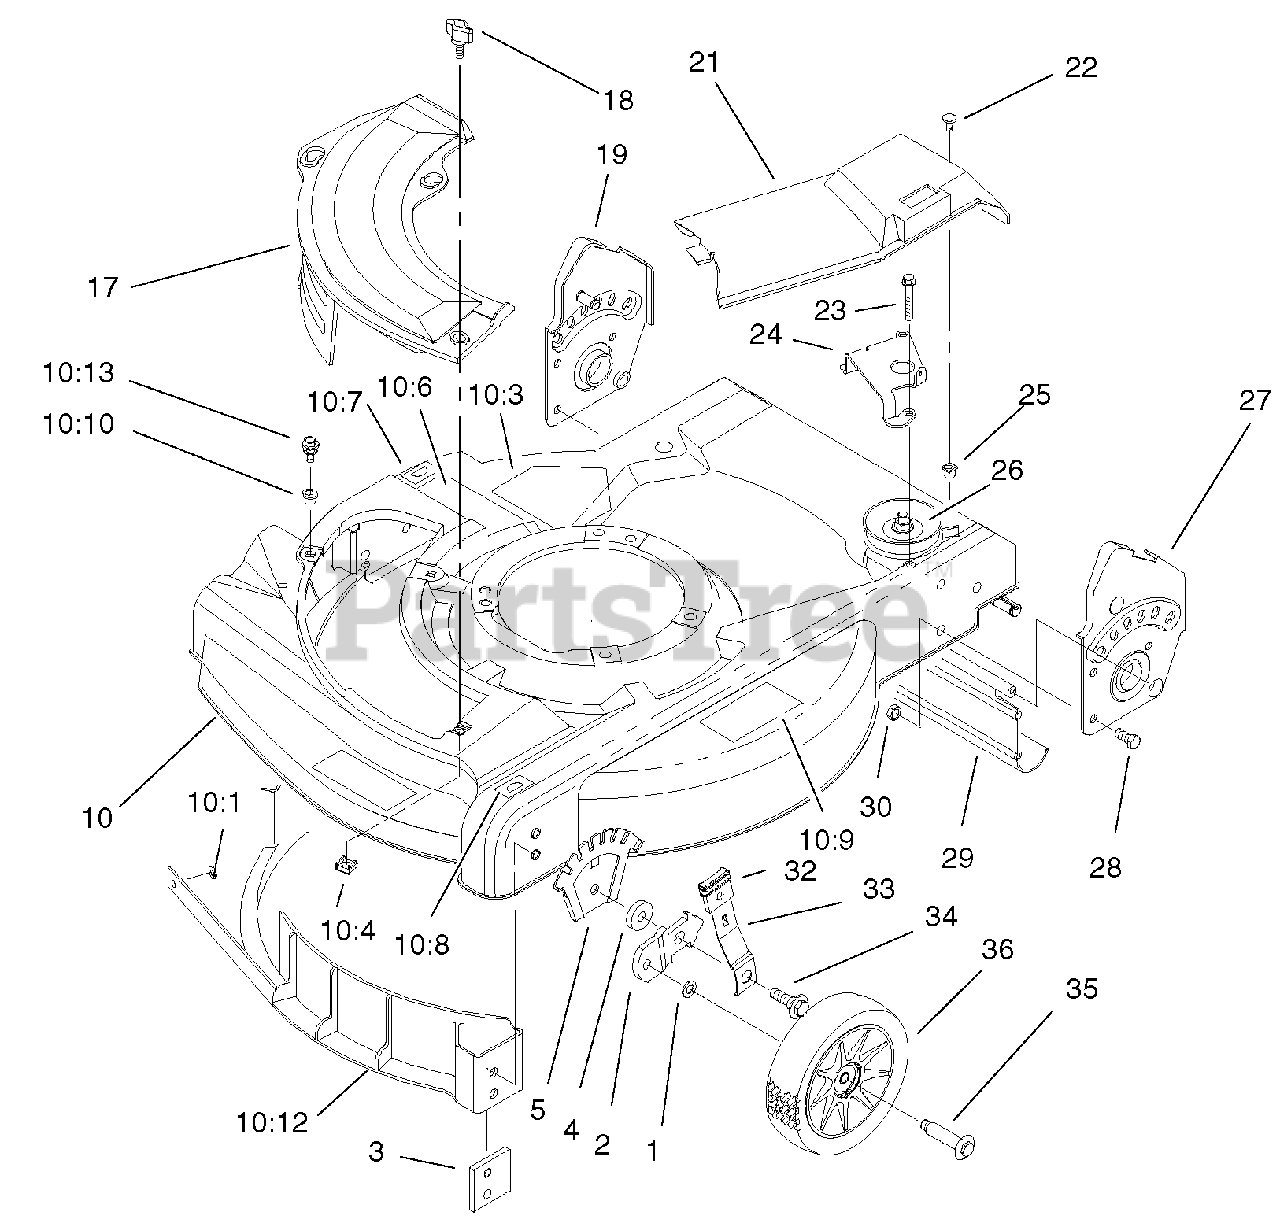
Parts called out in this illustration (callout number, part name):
2	BRACKET-HEIGHT ADJUSTMENT, WHEEL
3	PLATE - BAFFLE
4	WASHER-WHEEL
5	PLATE - HEIGHT ADJUSTMENT
10	DECK ASM
10:1	WASHER-FLAT
10:3	DECAL-DANGER
10:4	NUT-CAGE
10:6	DECAL - WARNING
10:7	DECAL - HOC, RH
10:8	DECAL - HOC, LH
10:9	DECAL-WARNING
10:10	GROMMET - PLASTIC
10:12	Insert-Housing
10:13	SCREW-SEMS
17	PLATE-MULCH
19	HANDLE BRACKET ASM-RH
21	COVER - DRIVE
23	SCREW-HWHTF
24	GUIDE - TRANSMISSION
25	GROMMET
26	GEAR CASE ASM
27	HANDLE BRACKET ASM-LH
28	SCREW-HH
29	SHIELD - TRAILING
30	NUT-LOCK, NI
32	KNOB-LEVER, HEIGHT ADJUSTMENT
33	ARM-FRONT SPRING
34	BOLT-SHOULDER
35	BOLT-SHOULDER
36	WHEEL & TIRE ASM
